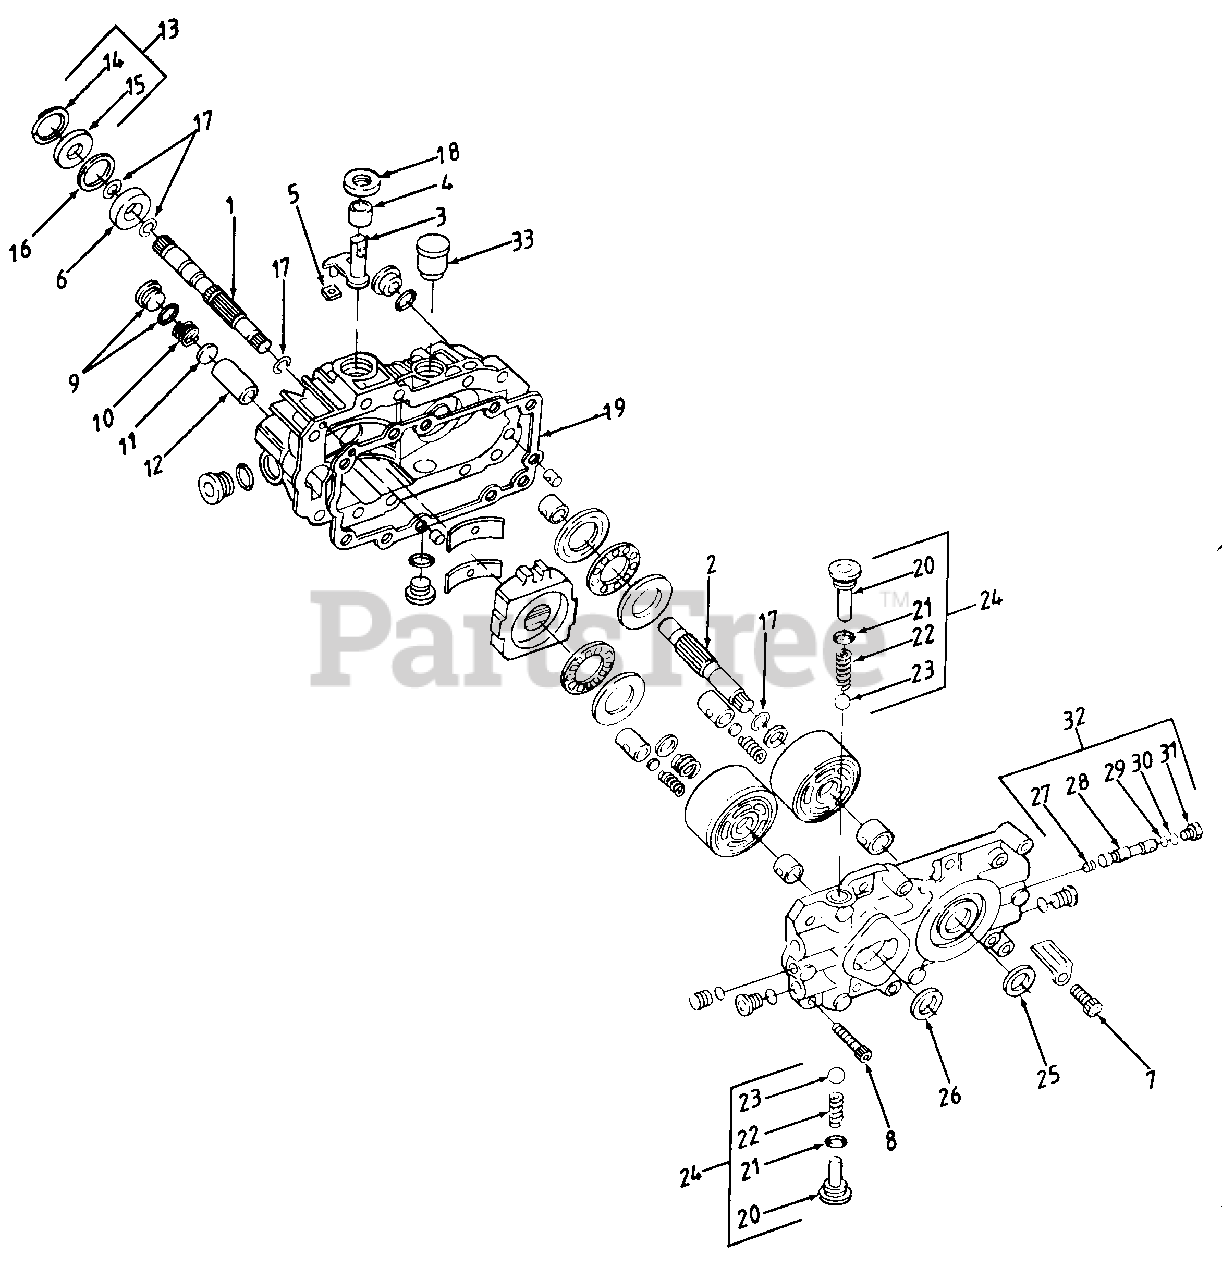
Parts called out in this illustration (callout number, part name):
1	Shaft Pump
2	Shaft Motor
3	Arm: Trunnion
4	Bearing: Journal
5	Guide: Slot
6	Bearing: Ball
7	Screw: Socket Head
8	Screw: Socket Head
9	Plug
10	Spring: Filter
11	Washer: Filter
12	Filter
13	Kit: Seal
14	Ring: Retaining
15	Seal: Lip
16	Spacer
17	Ring: Retaining
18	Seal: Lip
19	Gasket
21	O-Ring
24	Kit: Check Valve
25	Seal: Lip
26	Seal: Lip
27	Spring
28	Spool: Bypass
29	O-Ring
30	O-Ring
32	Kit: Bypass Valve
33	Reservoir
